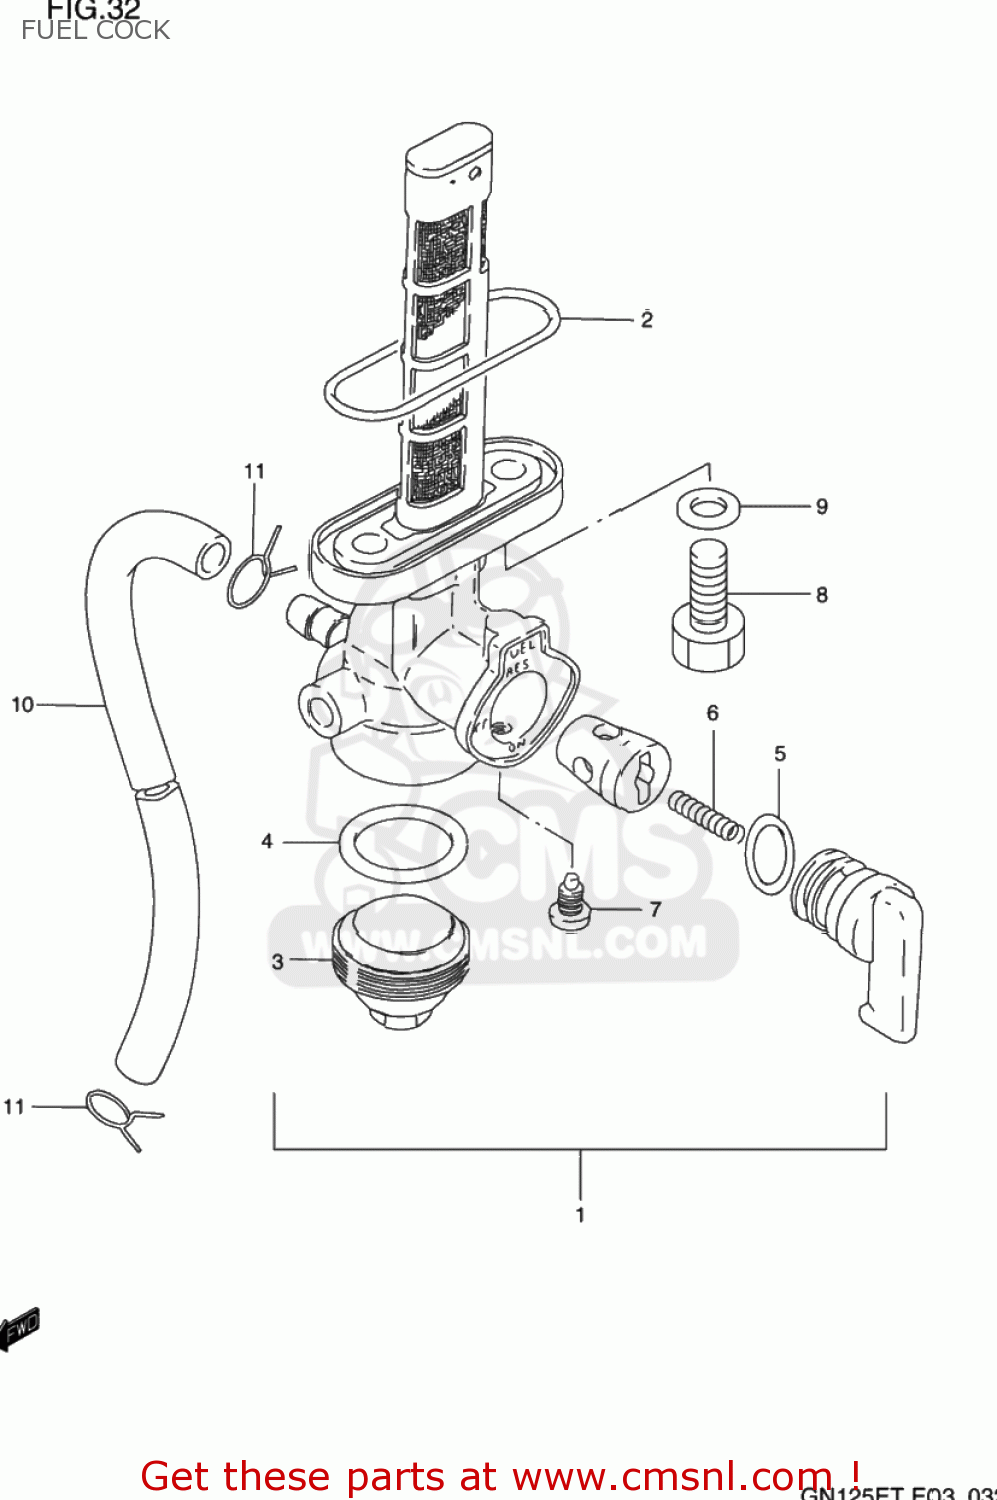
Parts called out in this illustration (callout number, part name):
1	COCK ASSEMBLY,FUEL
2	O RING,FUEL COCK
3	CUP,STRAINER
4	GASKET,FILTER (NAS)
5	O-RING,LEVER
6	SPRING
7	SCREW
8	BOLT(6X20)
9	GASKET(6.4X11.5X0.8) (NAS)
10	HOSE(5X8.2X600)
11	CLIP
